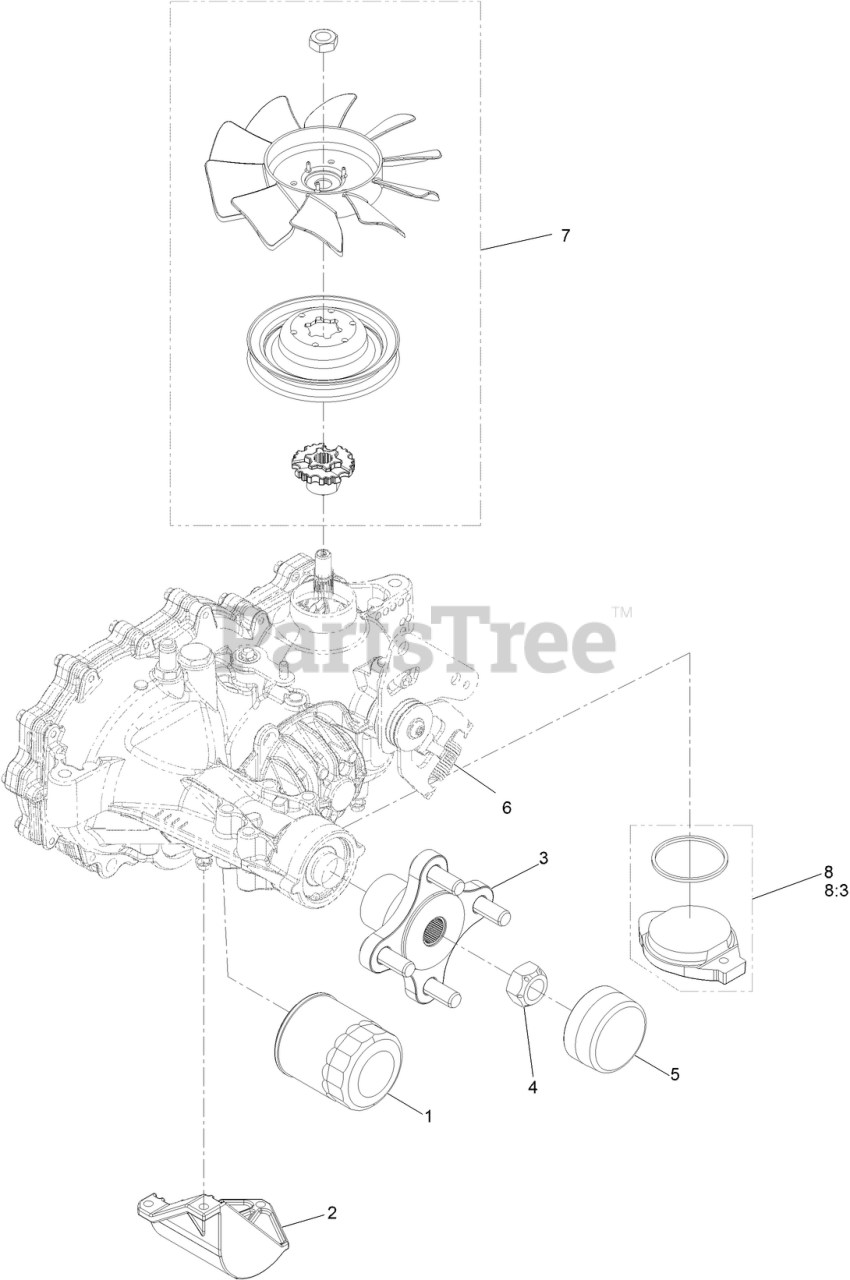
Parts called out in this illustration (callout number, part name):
1	ELEMENT-OIL FILTER, HYD
2	GUARD-FILTER, RH
2	FILTER GUARD KIT
3	HUB KIT
4	NUT-HUB
5	COVER-NUT, AXLE
6	SPRING-EXTENSION
7	KIT-FAN & PULLEY
8	CHARGE KIT
8:3	O RING-SEAL
